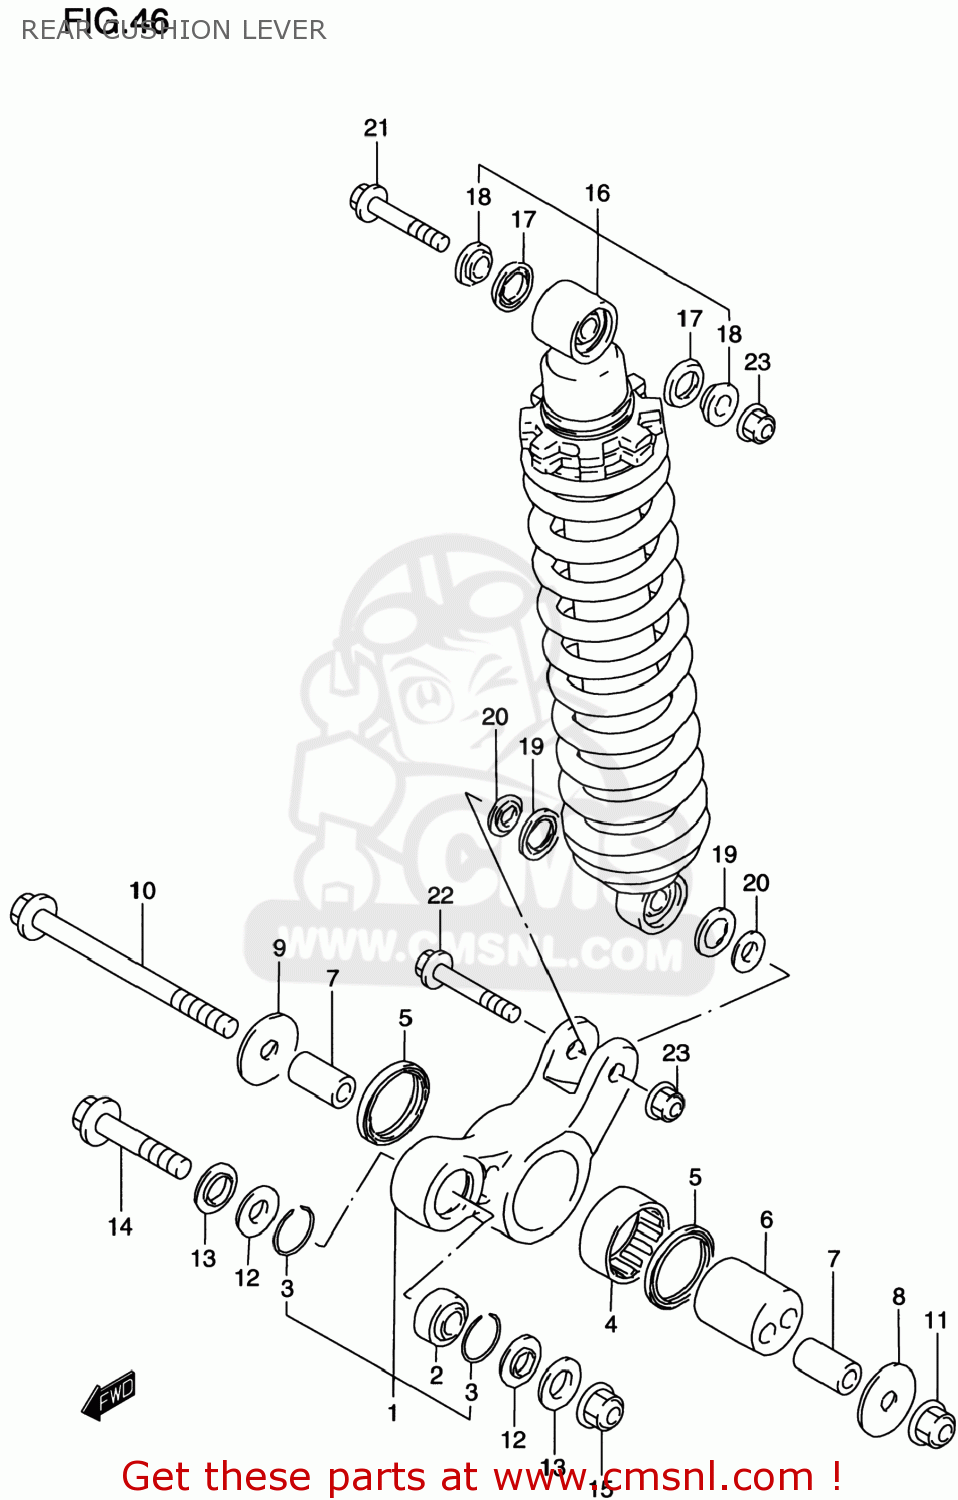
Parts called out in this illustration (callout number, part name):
1	LEVER SET,RR CUSHION
2	BEARING(12X26X16)
3	RING,BEARING STOPPER
4	BEARING(37X47X20)
5	SEAL,DUST
6	SPACER,RR SUSPENSION ECCENTRIC
7	SPACER,CUSHION LEVER SHAFT
8	WASHER,RR CUSH LVR CTR,L
9	WASHER,RR CUSH LVR CTR,R
10	SHAFT,RR CUSHION LEVER CTR
11	NUT 12MM
12	SEAL,RR CUSHION ROD DUST
13	SPACER,RR CUSHION ROD
14	BOLT,CUSHION LEVER FR
15	NUT 12MM
16	ABSORBER ASSEMBLY,REAR SHOCK
17	DUST SEAL
18	SPACER
19	DUST SEAL,RR SHOCK
20	COLLAR
21	BOLT,REAR SHOCK ABSORBER
22	BOLT(10X48)
23	NUT
